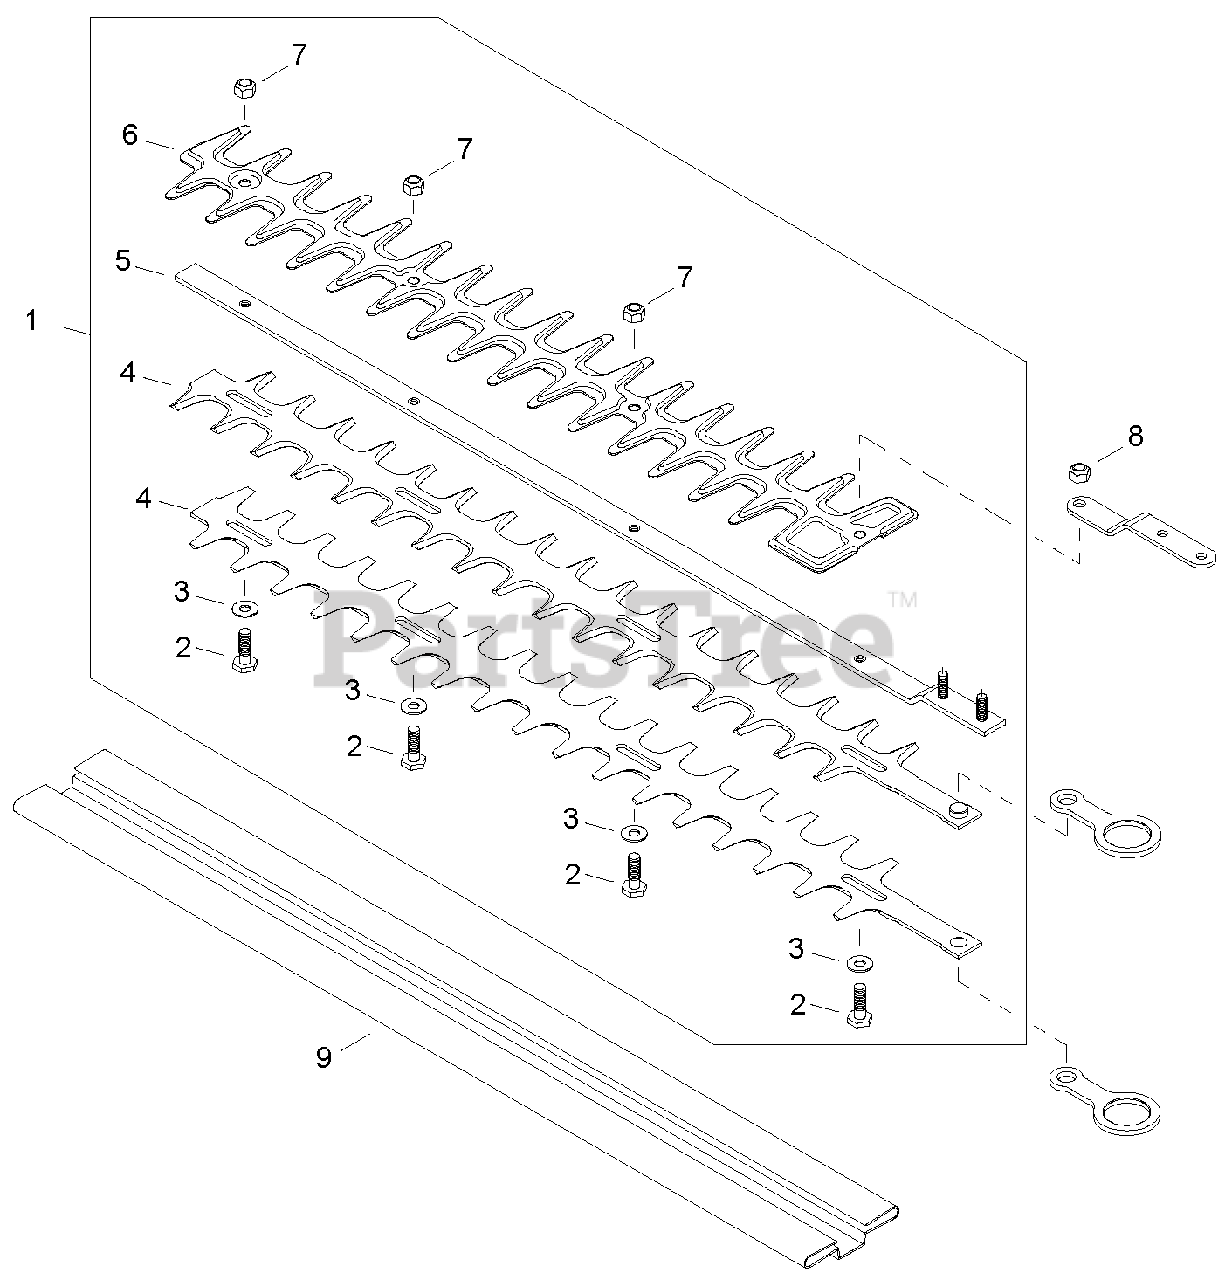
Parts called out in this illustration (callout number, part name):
2	BOLT
3	WASHER
4	BLADE KIT - 22" (55cm) CHROME
5	GUIDE BAR - 22" (56cm)
6	GUARD, CUTTER BLADE
7	LOCKNUT - 6
8	LOCKNUT - 6
9	COVER, BLADE
13-1	BLADE KIT - 22" (55cm)
